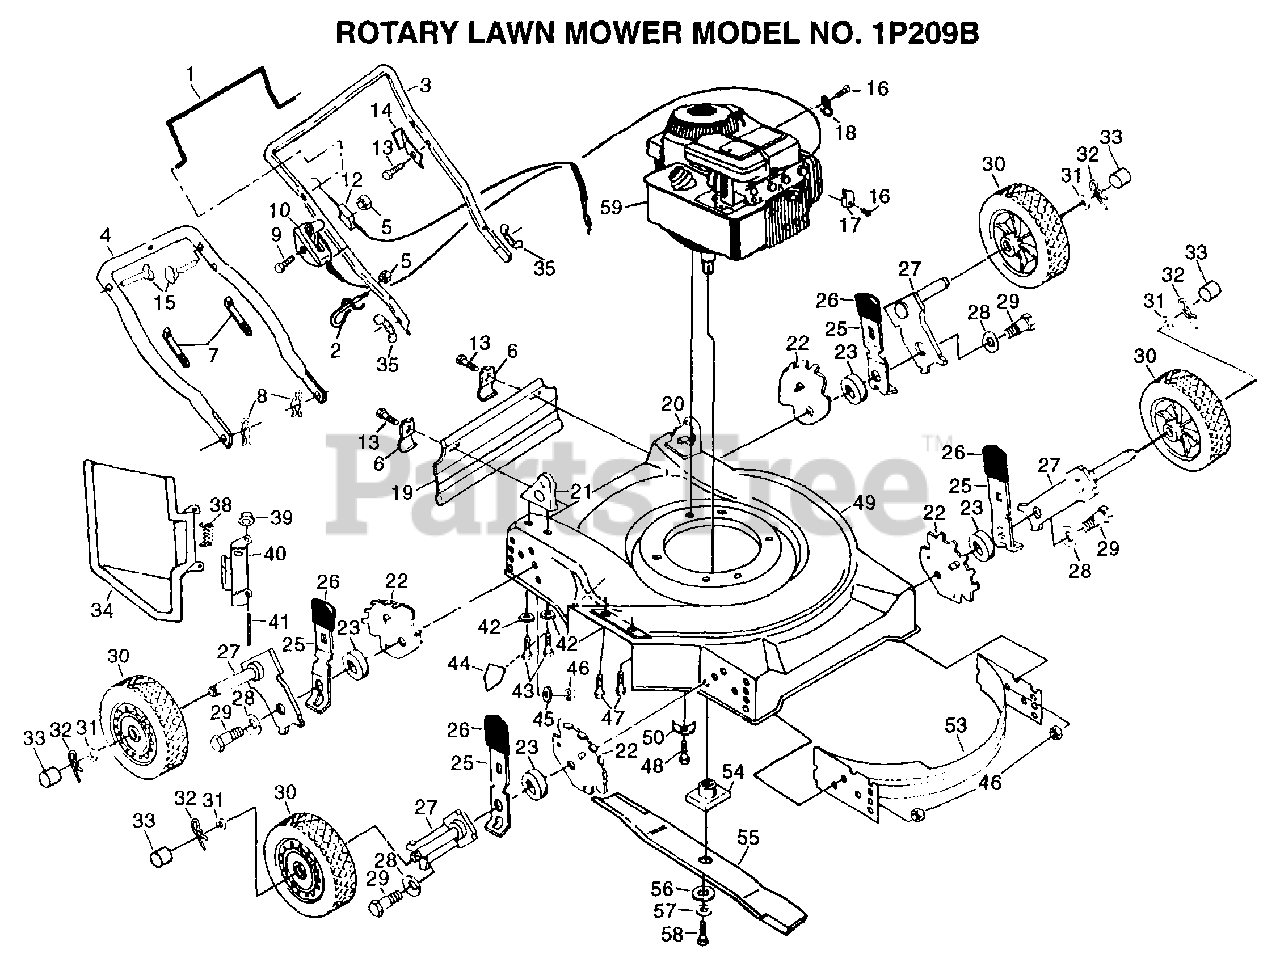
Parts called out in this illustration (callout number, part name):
1	CONTROL BAR PM
2	ROPE GUIDE
6	"BRKT,DEFL PM"
8	HAIRPIN COTTER
9	SCREW.HXHD.WASH.
10	CONTROL THROTTLE
12	"CABLE,ENG ZONE CO"
13	TAPPING SCREW
14	"BRKT,UPSTOP"
15	BOLT.HANDLE.LM
16	SCREW PM
17	CABLE CLAMP
18	GUIDE CLIP PM
19	SKIRT.RD.20/22
22	BRACKET.ADJ.9POS.
25	SPRING SELECTOR
26	KNOB PM
27	AXLE ARM
28	"WASHER, BELLEVIL."
29	BOLT SHLD 3/8-16
30	WHEEL&TIRE
31	WASHER
32	RETAINER CLIP PM
33	HUB CAP-PLASTIC
34	"GRD,DISCHARGE"
35	"NUT,WING PM"
38	"SPRING,TORSION"
39	PUSH ON SPEED NUT
40	"BRKT,HSG "
42	STEEL WASHER
43	SCREW
44	DECAL HYT
46	LOCKNUT PM
47	SCREW
48	SCREW
49	"KIT.HSG.20""SDPUSH"
54	BLADE ADAPTOR
55	BLADE.STAND.20INC
56	"WASHER,HARDEN"
57	LOCKWASHER
58	SCREW
